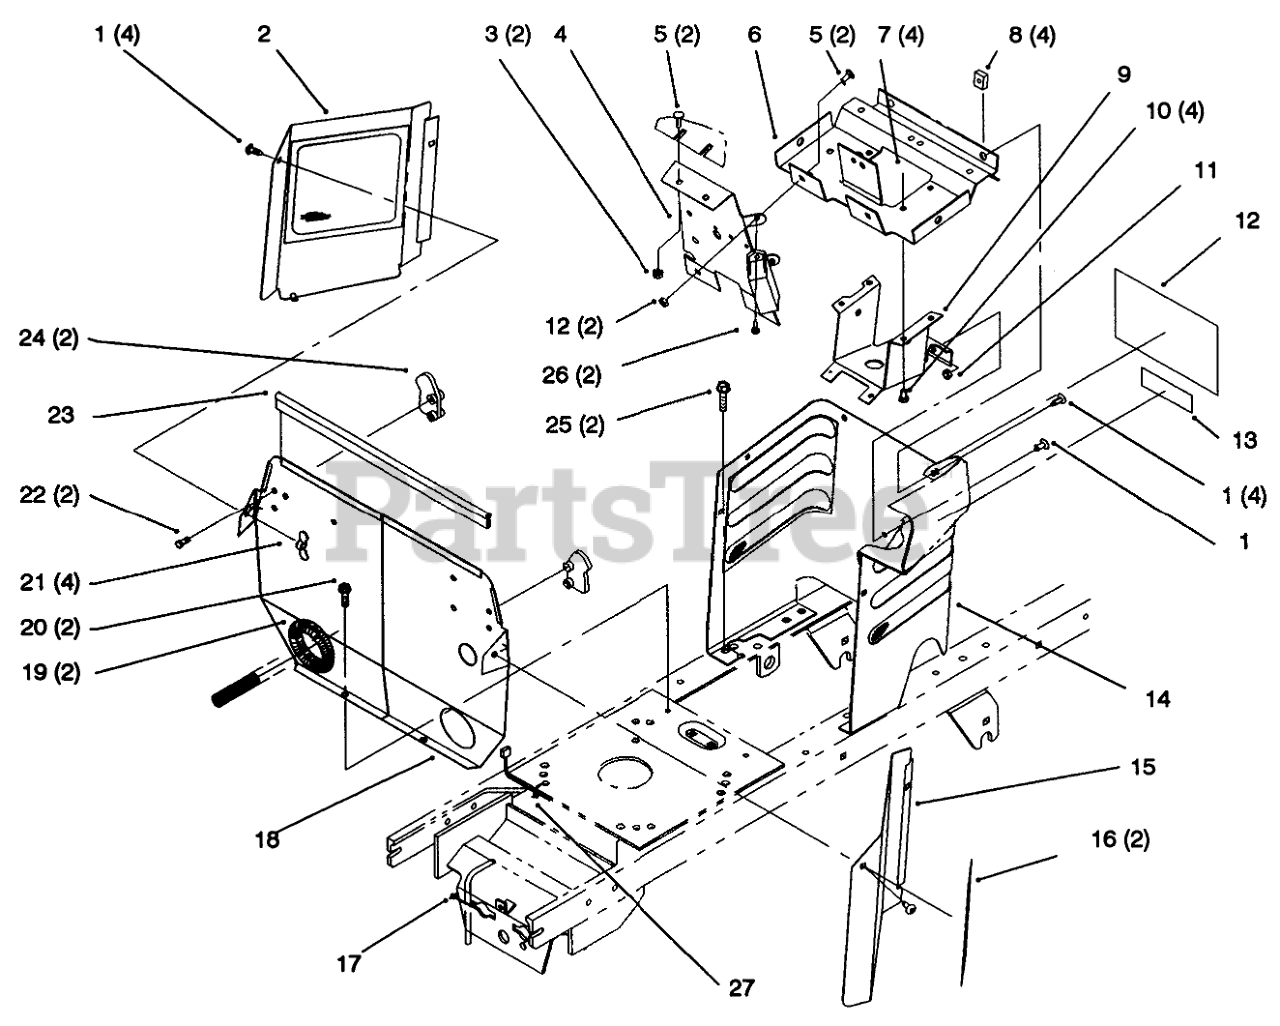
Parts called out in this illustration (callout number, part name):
1	SCREW-HH
2	Cover-Side RH
3	NUT-KEPS
4	Panel-Support
5	SCREW-CARR
6	Support-Dash
7	NUT-HEX
8	NUT RETAINER - J TYPE
9	Support-Column
10	SCREW-HH
11	NUT-LOCK, NI
12	DECAL-DANGER
13	DECAL-INSTRUCTION
14	Hoodstand W/Decals
15	Cover-Side LH
16	DECAL - 269-H
17	TIE-CABLE
18	Firewall
19	COVER-SHAFT, DRIVE
20	SCREW-HWH
21	NUT-WING
22	SCREW-PLASTITE
23	TRIM-SEAL, FIREWALL
24	LATCH-HOOD
25	SCREW-HWHTF
26	SCREW-PPHTF
27	TIE-CABLE
